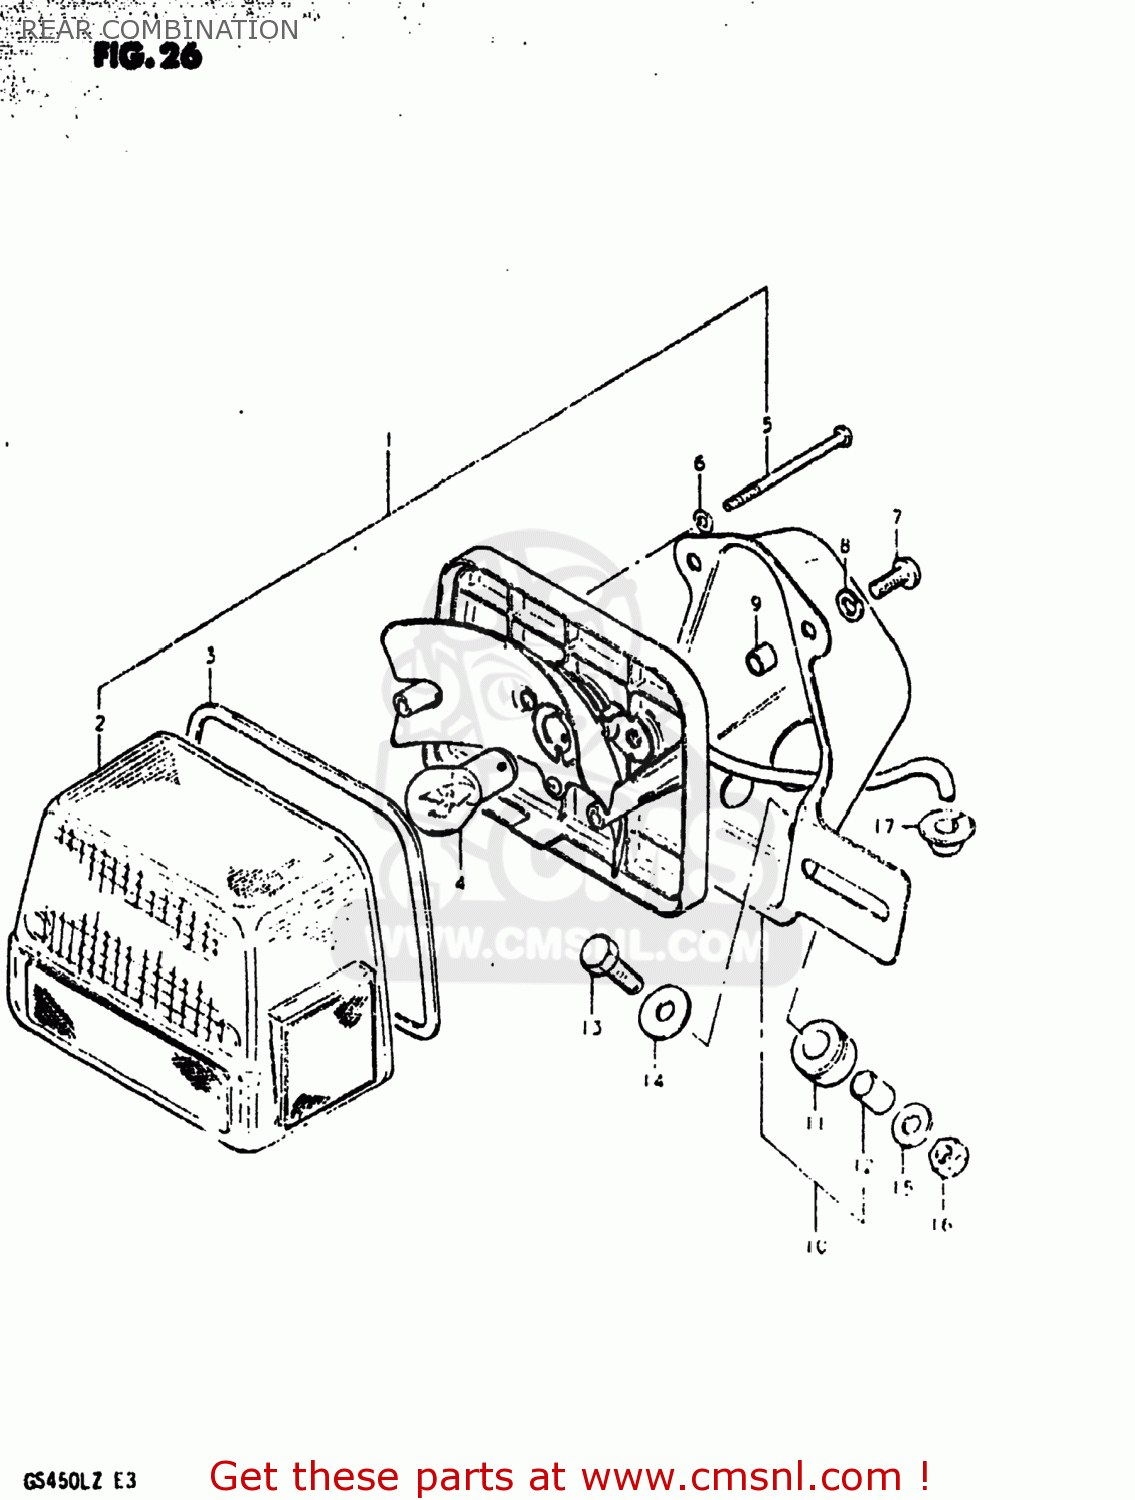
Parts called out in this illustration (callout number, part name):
1	LAMP UNIT,REAR COMBINATION
2	LENS
3	GASKET (NAS)
4	BULB(12V23W)
5	SCREW
6	GASKET (NAS)
7	SCREW
8	LOCK WASHER
9	SPACER
10	BRACKET UNIT,TAIL LAMP
11	CUSHION
12	SPACER
13	BOLT
14	WASHER (6.5X20X1.2)
15	WASHER
16	NUT
17	GROMMET
